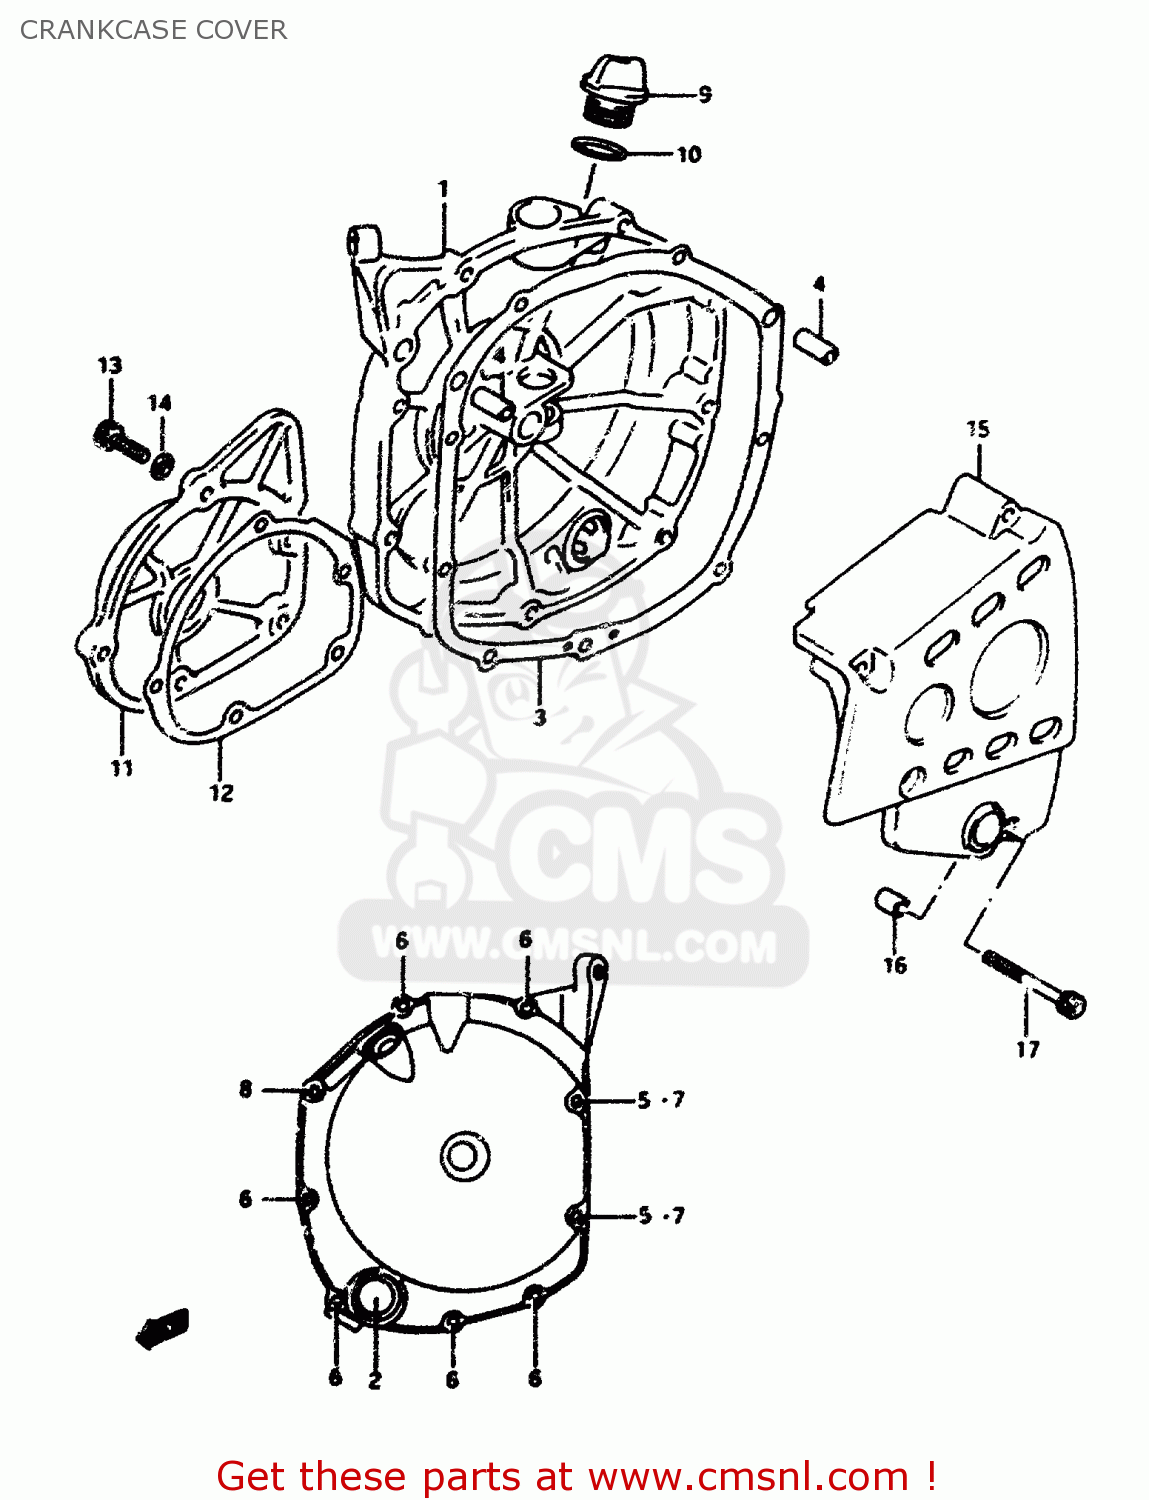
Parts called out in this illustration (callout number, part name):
1	COVER,CLUTCH
2	LENS,OIL LEVEL CHECK
3	GASKET,CL COVER (NAS)
4	PIN
5	GASKET(5.8X11X1.2) (NAS)
6	BOLT
7	BOLT
8	BOLT
9	PLUG
10	O RING(D:3.1,ID:16.8)
11	CAP
12	GASKET,SIGNAL GEN COVER
13	BOLT
14	GASKET(5.8X11X1.2) (NAS)
15	COVER,ENGINE SPROCKET
16	PIN
17	BOLT(6X50)
